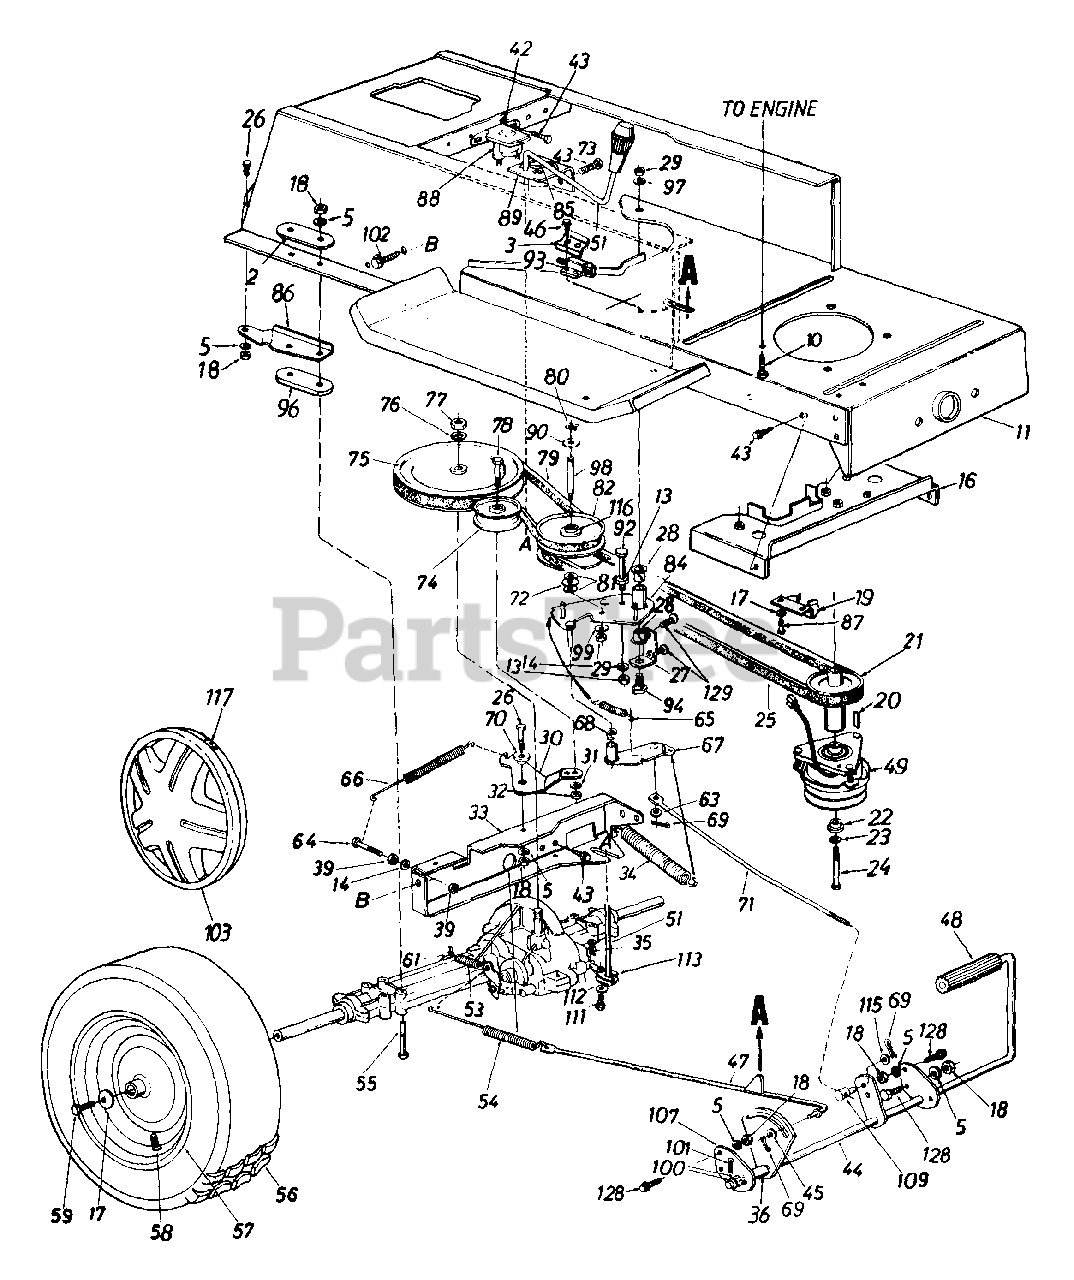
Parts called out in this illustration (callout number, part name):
3	Switch Plate
5	L-Wash. 5/16" I.D.
10	Hex Wash. Hd. TT-Tap Scr. 3/8-16 x 1" Lg.
11	Lower Frame Ass'y.
13	Hex Nut 1/4-20 Thd.
14	L-Wash. 1/4" I.D.
16	Belt Guard Brkt. Ass'y.
17	Bell-Wash. .345" I.D. x .88"
18	Hex Nut 5/16-18 Thd.
21	Engine Pulley
22	Shld. Spacer .445" I.D.
23	L-Wash. 7/16" I.D.
24	Hex Bolt 7/16-20 x 3.25" Lg.
25	Variable Speed Belt
26	Hex Bolt 5/16-18 x .75" Lg.
27	Bearing Shaft Bracket Ass'y.
28	Flanged Nyliner Brg. 5/8" I.D. x .88" Lg.
29	Hex Nut 3/8-24 Thd.
31	L-Wash. 3/8" I.D.
32	Hex Nut 3/8-24 Thd.
35	Internal Cotter Pin
36	Spacer .63" I.D.
39	Hex Nut 1/4-28 Thd.
42	Ext. L-Wash. 1/4" I.D.
43	Hex Wash. Hd. S-Tap Scr. 1/4-20 x .50" Lg.
46	Truss Mach. Scr. B-Tap Scr. #10 x .5" Lg.
47	Brake Rod Ass'y.
48	Foot Pad
49	Electric Clutch
51	Shift Lever Ass'y.
53	Ext. Spring .38" O.D. x 2.5"
53	Ext. Spring .59" O.D. x 7.08"
55	Hex Bolt 5/16-18 x 3" Lg.
57	Wheel Rim Only
58	Air Valve
59	Hex Bolt 5/16-24 x .75" Lg.
61	Brake Return Spring Anchor
63	Fl-Wash. .34" I.D. x .68" O.D.
64	Hex Bolt 1/4-28 x 1.25" Lg.
65	Ext. Spring
66	Ext. Spring .62" O.D. x 6.12"
68	Flanged Bearing
69	Cotter Pin 3/32" Dia.
70	Shoulder Spacer .27" Lg.
71	Speed Control Link
72	Truss Bearing .56" Dia. x 1.25"
73	Shift Knob
74	Fl-Idler Pulley 3.25" x .75"
76	Bell-Wash. .56" I.D. x 1.125"
77	Hex Jam Nut 5/16-18 Thd.
78	Hex Bolt 3/8-24 x 1.75" Lg.
79	Variable Speed Belt
80	Snap Ring .56" Dia.
82	Variable Speed Pulley Ass'y. 5" O.D.
88	Solenoid
90	Teflon Washer .565" I.D.
92	Hex Bolt 1/4-20 x 3.5" Lg.
93	Safety Switch (Clutch)
94	Shld. Bolt 3/8-24 x 3.12" Lg.
97	Bell-Wash. .38" I.D. x .88"
98	Shaft .56" Dia. x 3.875" Lg.
99	Bell-Wash. .39" I.D. x 1.12"
100	Fl-Wash. .64" I.D. x .94"
101	Cotter Pin 1/8" Dia. x 1.25"
102	Hex Wash. Hd. Scr. 5/16-18 x .62" Lg.
103	Hub Cap
109	Ferrule
111	Hex Bolt 1/4-28 x .50" Lg.
112	Bell-Wash. .265" I.D. x .75"
113	Shift Lever Link Ass'y.
115	Fl-Wash. .385" I.D. x .62"
116	Needle Brgs.
117	Spring Clip
128	Hex Wash. TT-Tap Scr. 5/16-18 x .75" Lg.
129	Hex Wash. AB-Tap Scr. 5/16-18 x .75" Lg.
